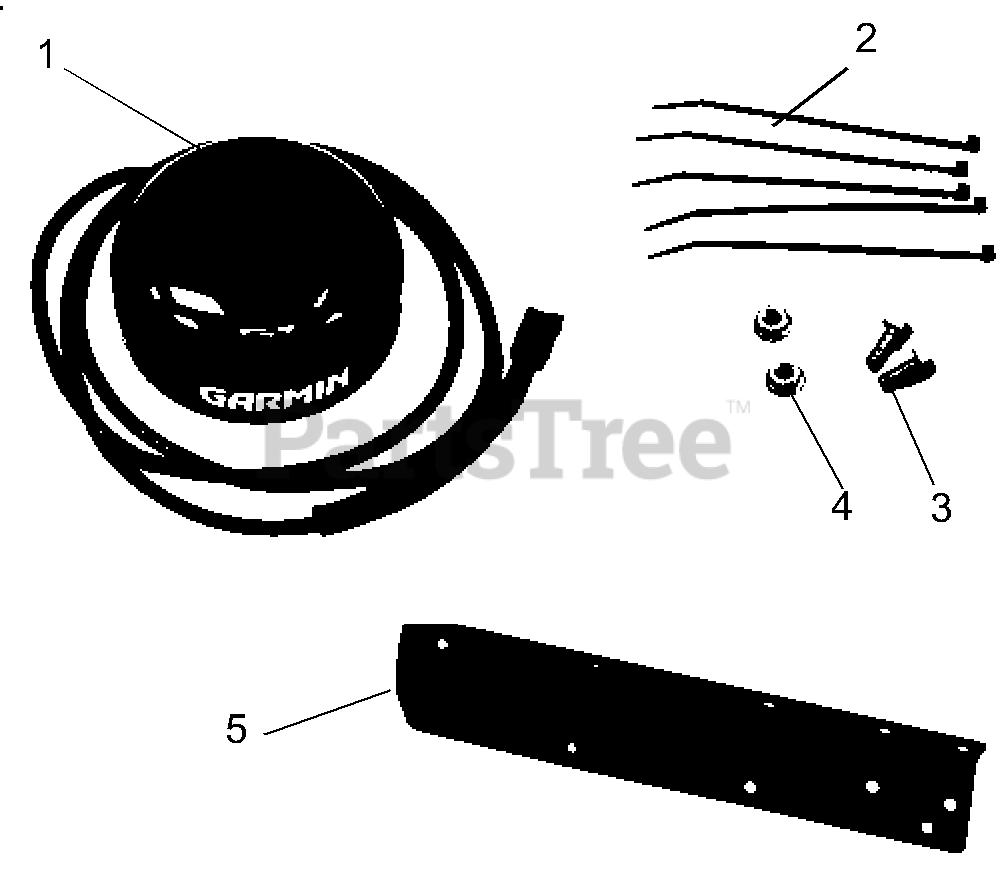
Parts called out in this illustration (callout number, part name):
1	Eye-Q(TM) GPS with Harness
2	Cable Tie, 5-1/2"
3	5/16"-18 x 3/4" Hex Bolt Grade 5
4	5/16"-18 Top Locking Flange Nut
5	Eye-Q(TM) GPS Mounting Bracket
